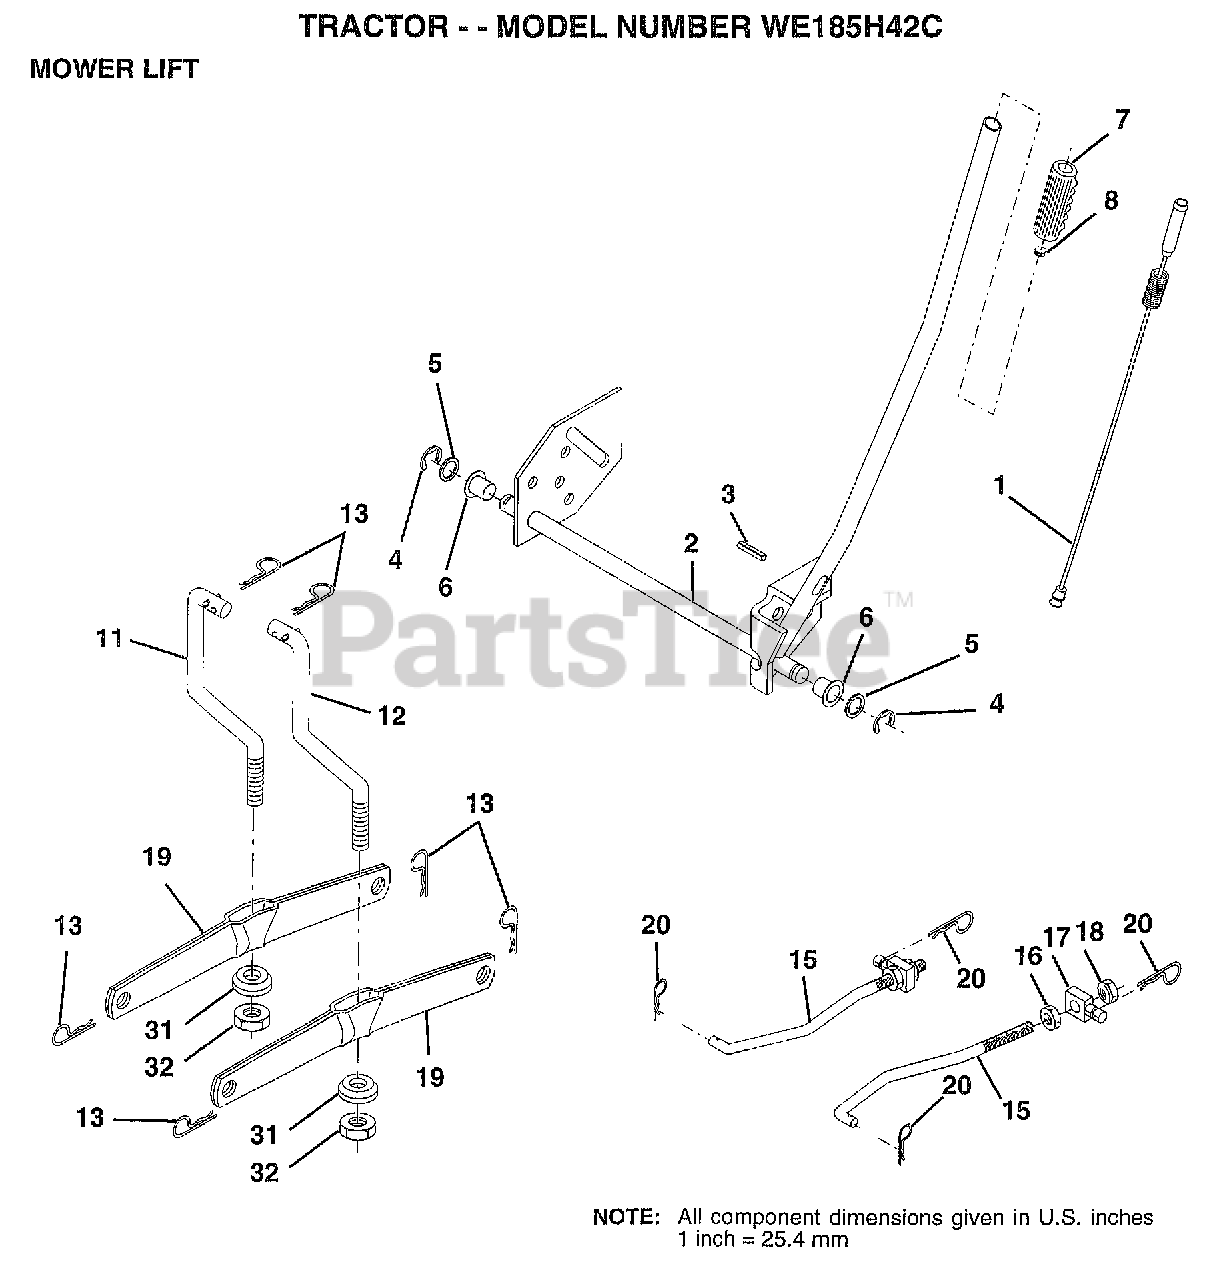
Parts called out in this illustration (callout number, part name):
1	WIRE ASM W.SPRING
2	"SHAFT ASM LIFT,RH"
3	PIN-GROOVE LT
5	WASHER
6	NYLON BEARING
7	GRIP
15	LINK.FRONT
16	NUT
17	TRUNION
18	NUT.LK.W/WSH.1/2.
19	ARM SUSP REAR
20	RETAINER.SPRING
31	BEARING PVT LH
32	NUT.CROWNLOCK.3/8
